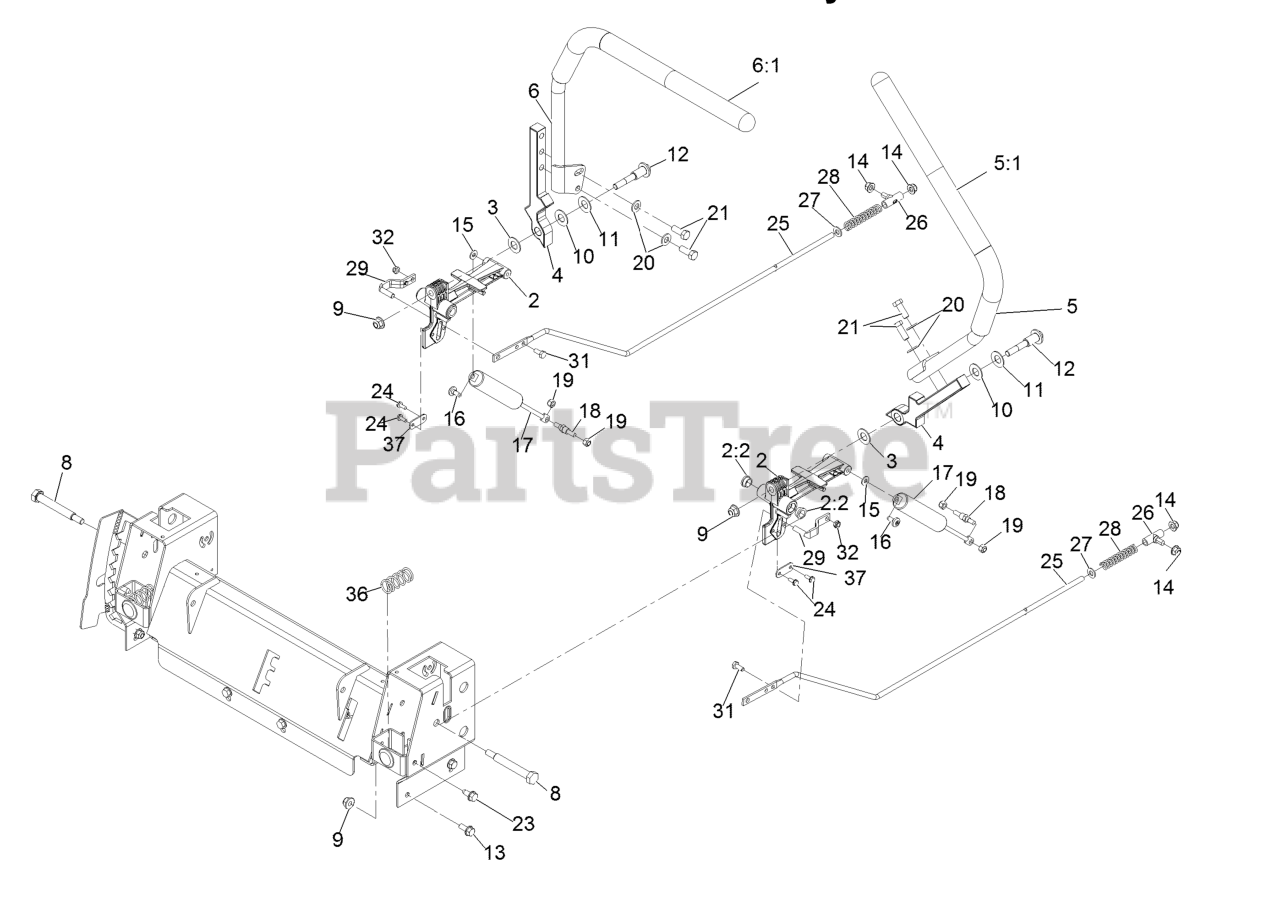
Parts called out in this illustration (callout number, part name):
2	ACTUATOR ARM ASM
2:2	BUSHING-FLANGE
3	WASHER-NYLON
4	ARM-CONTROL
5	HANDLE-CONTROL, LH
6	HANDLE-CONTROL, RH
8	BOLT-PIVOT
9	NUT-HF, NI
11	WASHER-BELLEVILLE
12	BOLT-PIVOT
13	SCREW-HHF
14	NUT-HF, NI
16	SCREW-SHOULDER
18	STUD-DAMPER
19	NUT-LOCK, NI
20	WASHER-FLAT
21	SCREW-HH
23	Screw-HWH 5/16-18 X 3/4 Tf
24	SCREW-TAPTITE
25	ROD-HYDRO
26	MOUNT-ROD, HYDRO
27	WASHER-PLAIN
28	SPRING-RETURN, NEUTRAL
29	PIN-ROD, HYDRO
31	SCREW-HH
32	NUT-LOCK, NI
36	SPRING-RETURN
37	PLATE-STOP, HYDRO
